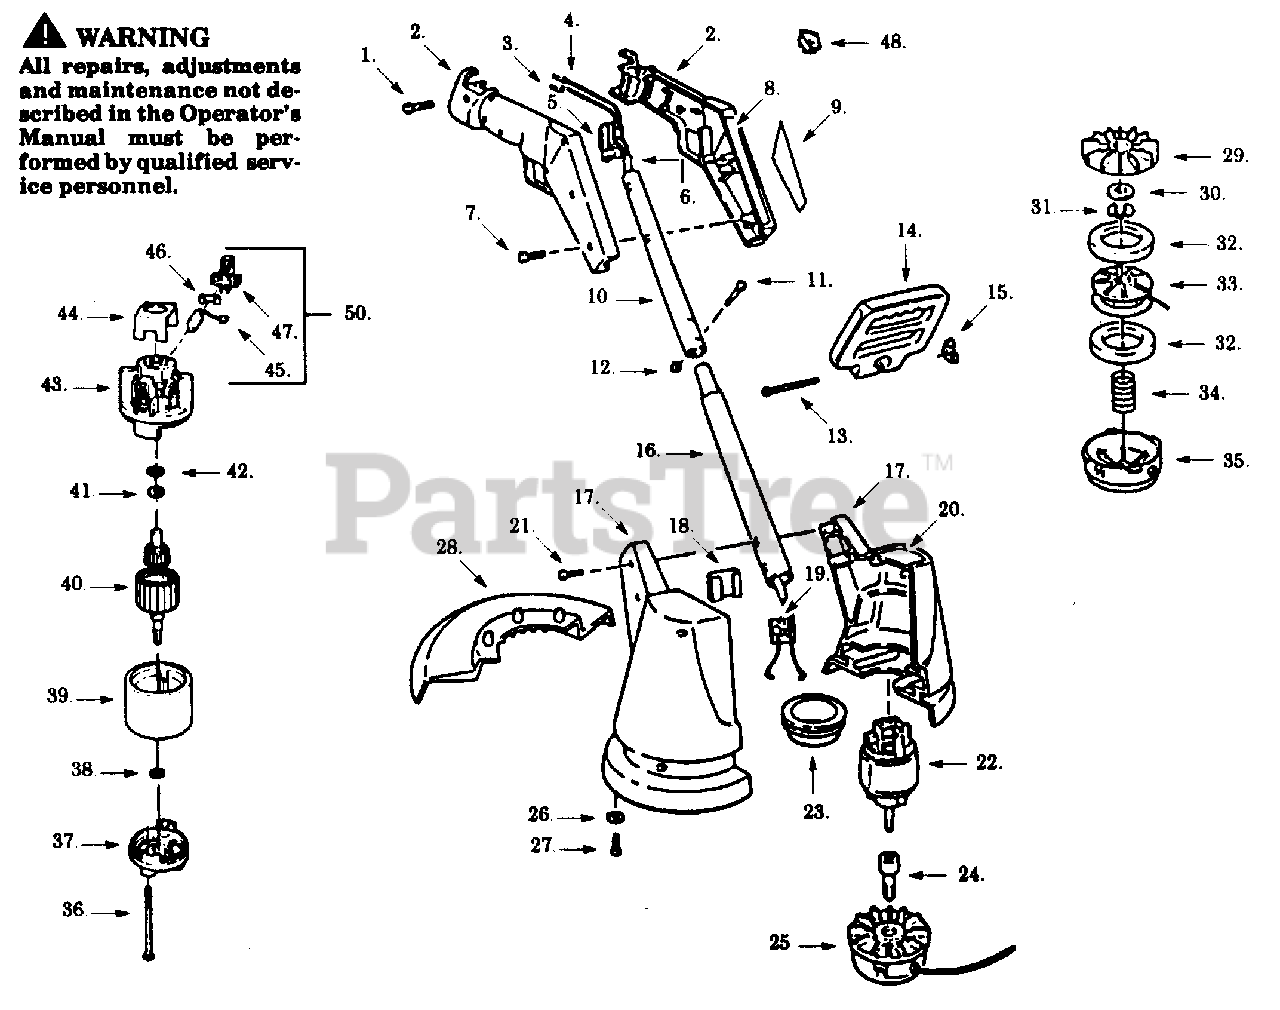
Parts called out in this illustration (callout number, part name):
2	Handle Set
3	Wire Blade Ass'y.
4	Wire Blade Ass'y.
5	Trigger Switch
8	Handle Label (Not a serviceable part)
9	Warning Label
10	Upper Tube
12	Stop Nut
14	Assist Handle
15	Wing Nut
16	Lower Tube
17	Housing Set
18	Insulator Shield
19	P.C. Board Ass'y.
20	Housing Label (Not a serviceable part)
22	Motor Ass'y.
23	Air Baffle
24	Shaft Adapter
25	Cutting Head Ass'y.
28	Guard & Blade Ass'y.
29	Rear Plate
31	Retaining Ring
32	Foam Pad
33	Spool & Line
35	Hub Ass'y.
37	Endbell Ass'y. (Drive)
39	Field Ass'y.
40	Armature Ass'y.
43	Endbell Ass'y. (Brush)
44	Insulator
45	Carbon Brush
46	Brush Spring
47	Brush Holder
48	Speed Switch
50	Brush Kit (Incl. 45,46,47)
